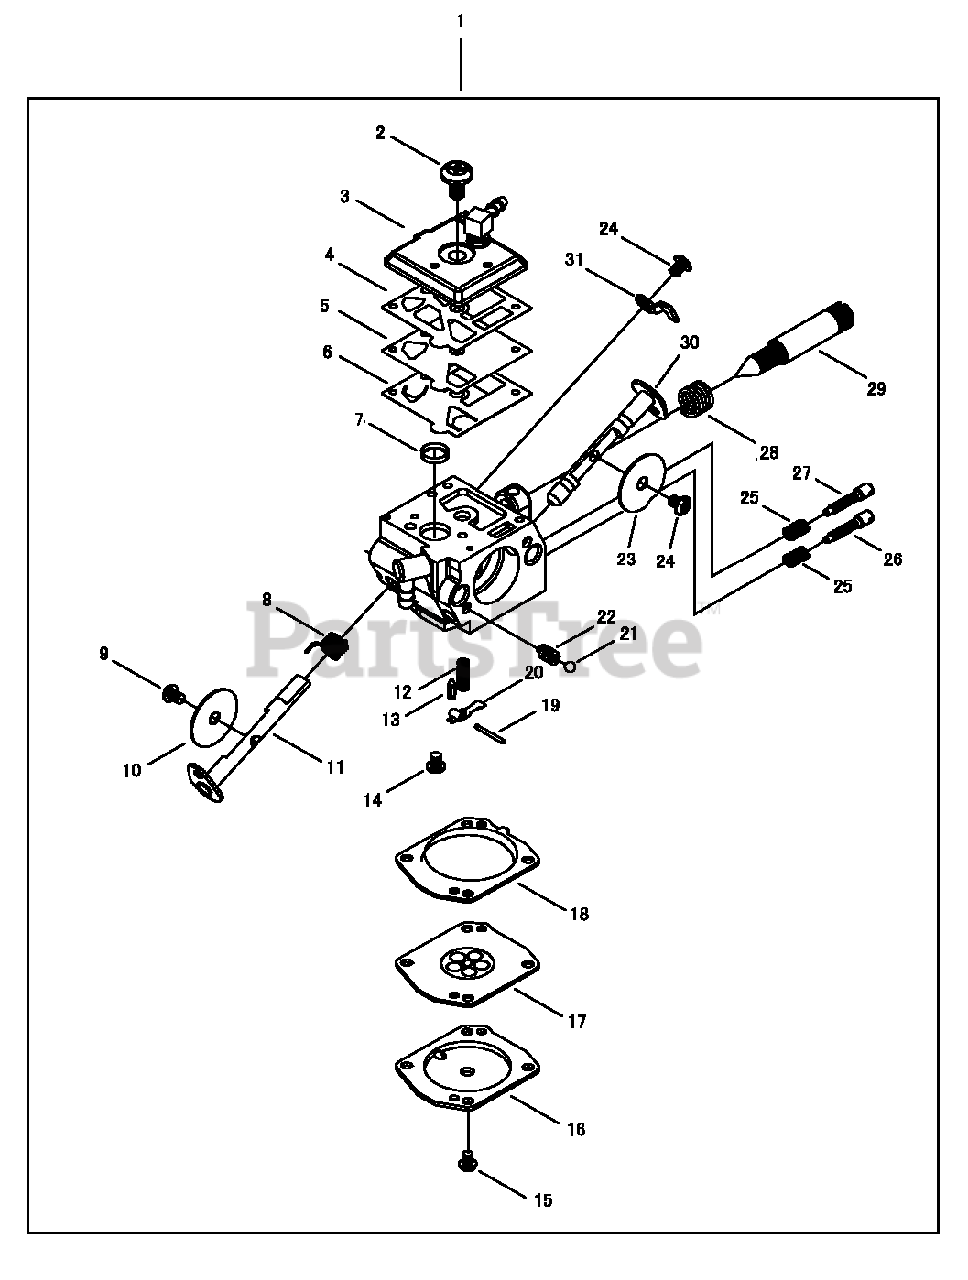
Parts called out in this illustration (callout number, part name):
1	CARBURETOR HDA-79C
2	SCREW, PUMP COVER
3	PUMP COVER ASSY
4	GASKET, PUMP
5	DIAPHRAGM, PUMP
6	DIAPHRAGM, PUMP
7	STRAINER
8	SPRING, THROTTLE RETURN
9	SCREW
10	VALVE, THROTTLE
11	SHAFT ASSY
12	SPRING, METERING LEVER
13	VALVE, INLET NEEDLE
14	SCREW, METERING LEVER PIN
15	SCREW
16	COVER, METERING
17	DIAPHRAGM, METERING
18	GASKET, METERING
19	PIN, METERING LEVER
20	LEVER, METERING
21	SPRING
22	BALL, CHOKE
23	VALVE, CHOKE
24	SCREW
25	SPRING
26	NEEDLE - HIGH SPEED
27	NEEDLE - LOW SPEED
28	SPRING, IDLE ADJUST
29	SCREW, IDLE ADJUST
30	SHAFT ASSY
31	STOP, THROTTLE
